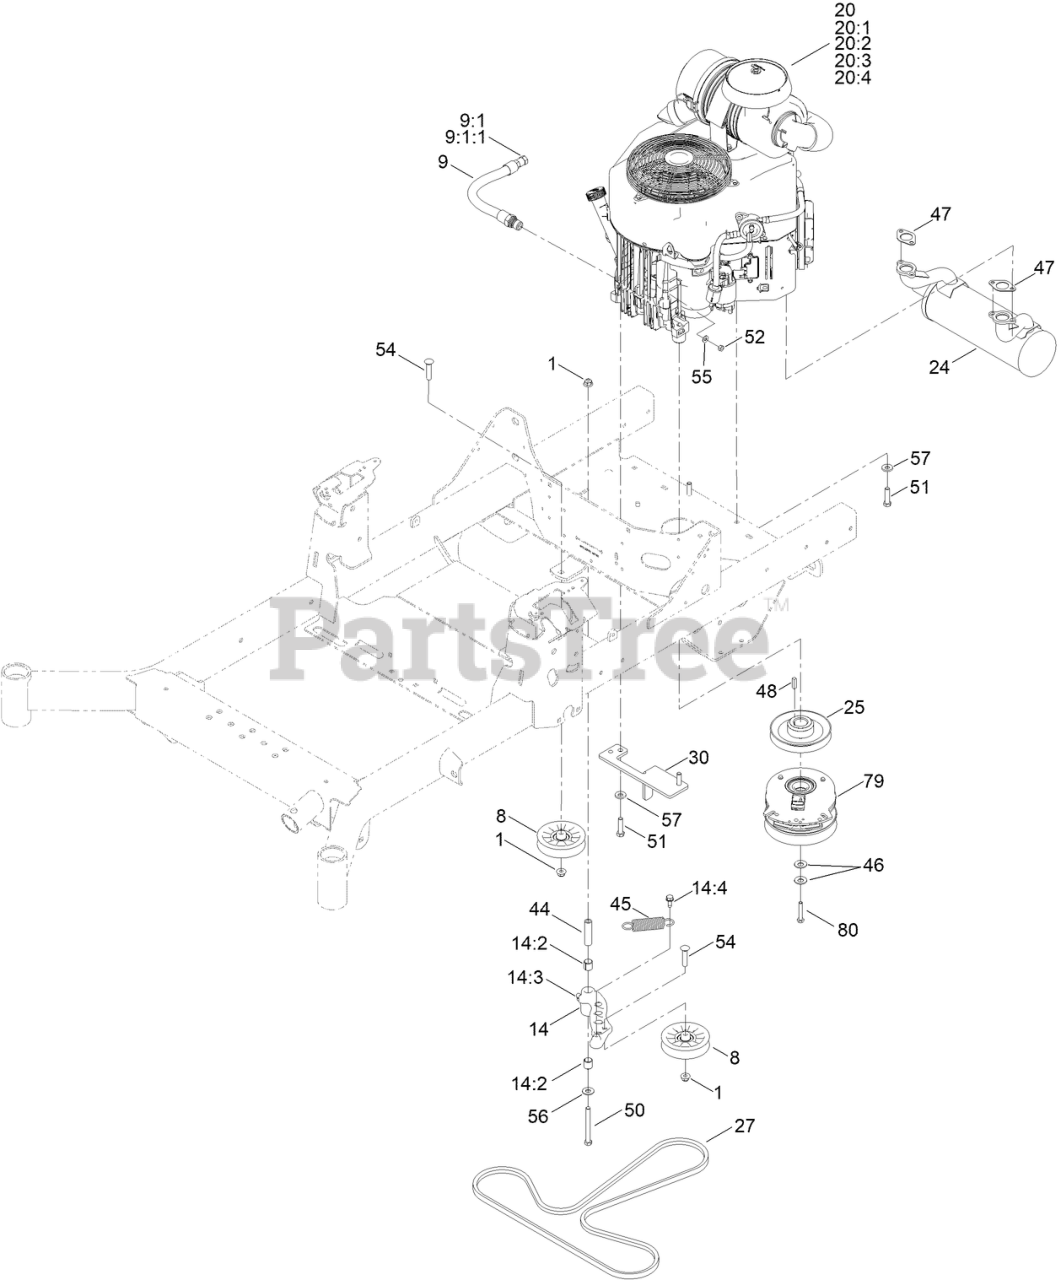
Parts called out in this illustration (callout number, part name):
1	NUT-HF, NI
8	PULLEY-FLAT IDLER
9	ENGINE OIL DRAIN HOSE ASM
9:1	PLUG-HH
9:1:1	O-RING
14	IDLER ARM ASM
14:2	SLEEVE-BEARING
14:3	FITTING-GREASE, 90 DEG
14:4	SCREW-THD ROLL, HWH
20:1	KAWASAKI 49065-7007 ENGINE OIL FILTER
20:2	KAWASAKI 49019-7005 FUEL FILTER
20:3	KAWASAKI 11013-7045 SAFETY FILTER
20:4	KAWASAKI 11013-7044 ENGINE AIR FILTER
24	MUFFLER
25	SHEAVE (W/HUB)
27	BELT-V
30	ANCHOR-CLUTCH
44	BUSHING-PIVOT, IDLER
45	SPRING-EXTENSION
46	WASHER-SPRING
47	GASKET-EXHAUST
50	SCREW-HH
51	SCREW-HH
52	NUT-HEX
54	SCREW-CARR
55	WASHER-FLAT
56	WASHER-FLAT
57	WASHER-BELLEVILLE
79	CLUTCH-PTO
80	SCREW-HH
